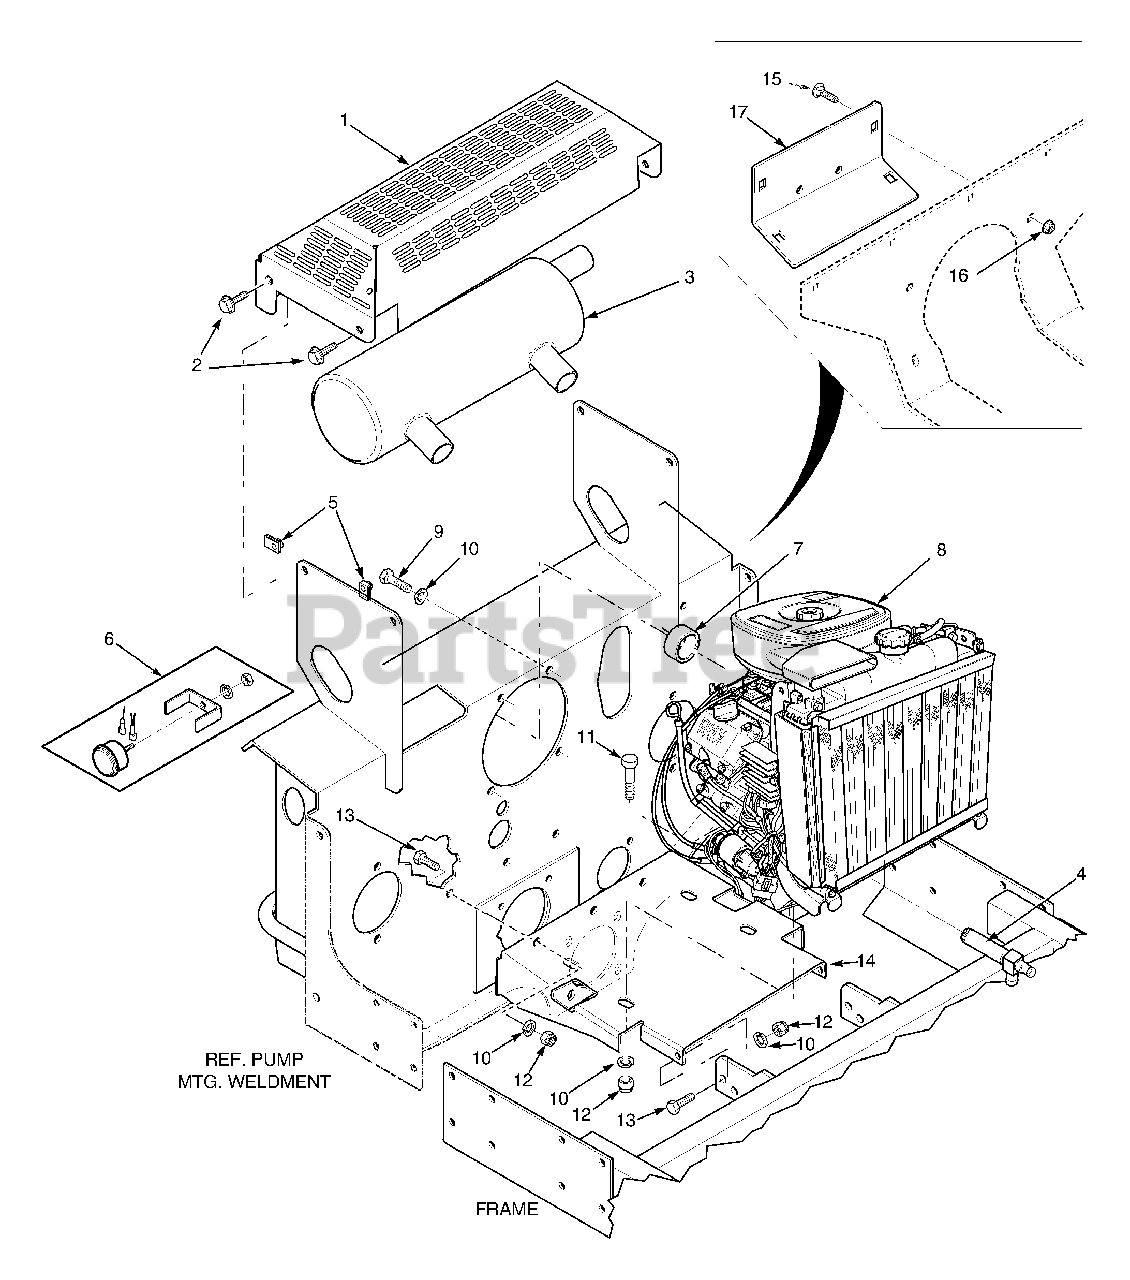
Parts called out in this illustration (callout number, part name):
1	Muffler Guard
2	Screw, Hex Serrated Flange 1/4-20 x 3/4"
3	Muffler
4	Extension, Oil Drain
5	U-Nut, 1/4-20
6	Hour Meter
7	Spacer, Engine (Kawasaki)
8	Engine, Kawasaki 23KA
9	Bolt, M10-1.50 x 25 Grade 8.8
10	Lockwasher, 3/8" Spring
11	Bolt, Hex Head 3/8-16 x 1-3/4"
12	Nut, Hex Elastic Stop 3/8-16
13	Bolt, Hex Head 3/8-16 x 1-1/4"
14	Plate, Engine Mounting
15	Bolt, Carriage 5/16-18 x 3/4"
16	Nut, Hex Serrated Flange 5/16-18
17	Rear Cover
